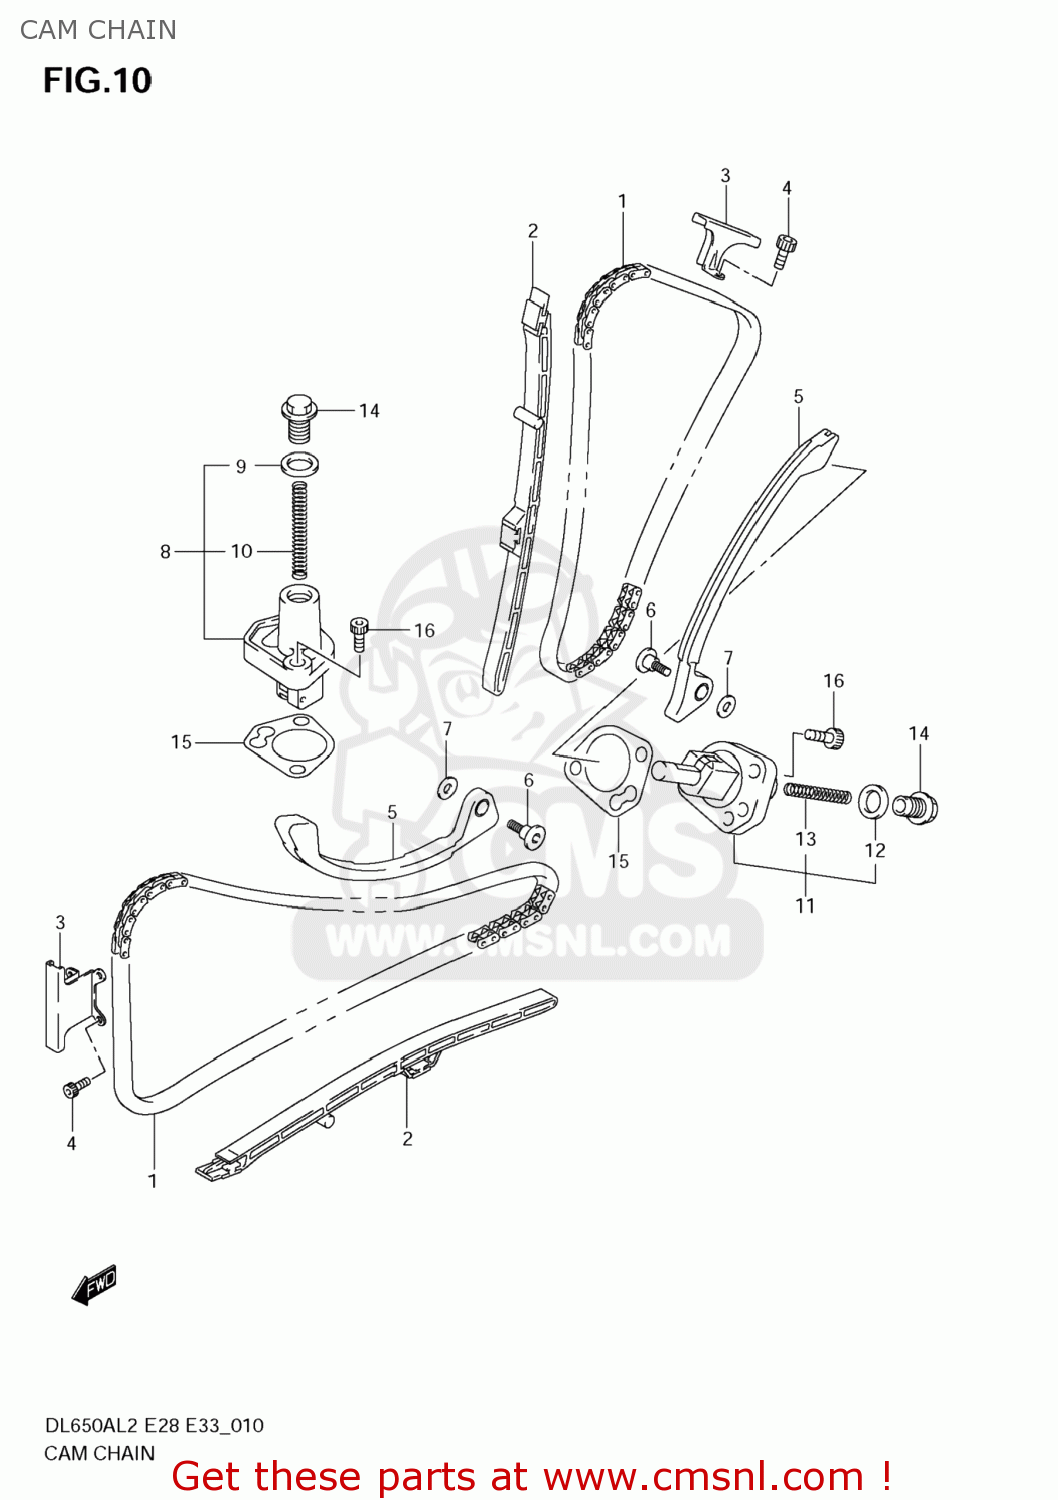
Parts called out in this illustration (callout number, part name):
1	CHAIN,CAMSHAFT DRIVE
2	GUIDE,CAM CHAIN NO.1
3	GUIDE,CAM CHAIN NO.2
4	BOLT
5	TENSIONER,CAM CHAIN
6	BOLT,CAM CHAIN TENSIONER
7	WASHER
8	ADJUSTER ASSY,TENSIONER FR
9	GASKET,TENSIONER ADJUSTER (NAS)
10	SPRING
11	ADJUSTER ASSY,TENSIONER RR
12	GASKET,TENSIONER ADJUSTER (NAS)
13	SPRING
14	PLUG,TENSIONER ADJUSTER
15	GASKET,TENSIONER ADJUSTER (NAS)
16	BOLT
